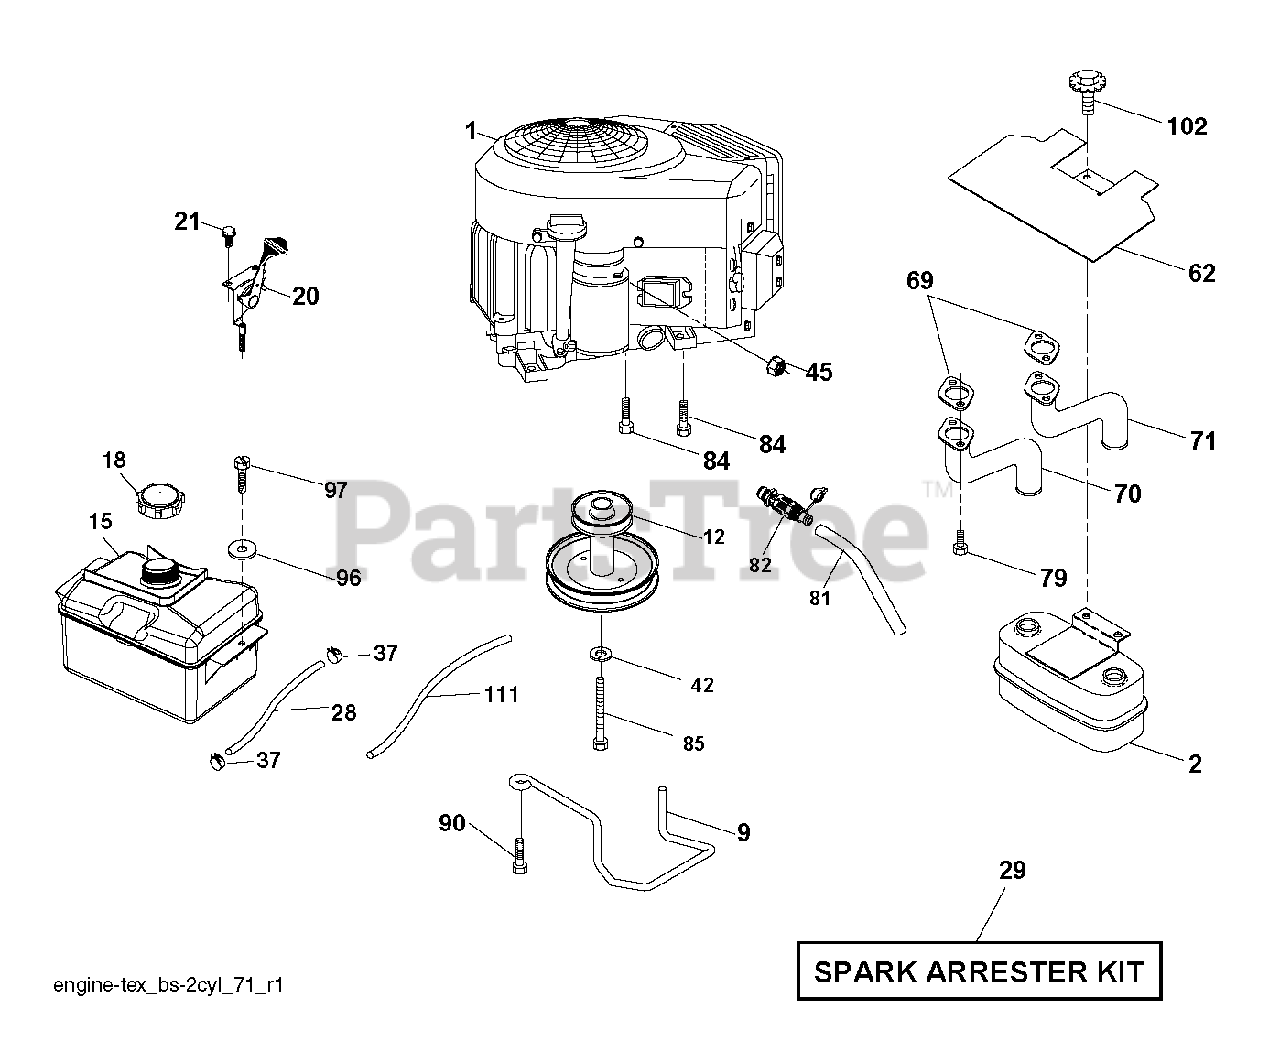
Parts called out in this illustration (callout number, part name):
2	MUFFLER.ASM.TWN.EXTNDED.DFLCTR
9	KEEPER.BELT.ENGINE
12	PULLEY.ENGINE.5.0.PD
15	TANK.ASM.FRT.2.5 GAL.W/CAP.EPA
18	CAP.FUEL.2 WAY VENT
20	CONTROL.TH/CK.COBRA.B&S.TWN.
21	SCREW.#10 X 0.750.BOS
28	LINE.FUEL.20"FRONT.EMI
29	KIT.SPARK ARRESTOR 794945 B&S
37	HOSE CLAMP
42	LOCKWASHER
45	NUT
62	SHIELD.HEAT.MUFFLER
69	GASKET.MUFFLER
70	EXHAUST.TUBE.LH.BS/TWIN
71	EXHAUST.TUBE.RH.B&S.TWIN.INTEK
79	SCREW.SOCKET.HEAD.5/16-18
81	TUBE, DRAIN OIL ASM.
82	VALUE.OIL.DRAIN
84	SCREW.3/8-16
85	BOLT HEX 7/16-20X4-1/4"
90	SCREW 3/8-16X1
97	SCREW HEXWSHR 1/4-20X3/4
102	SCREW
111	RP PURGE LINE
